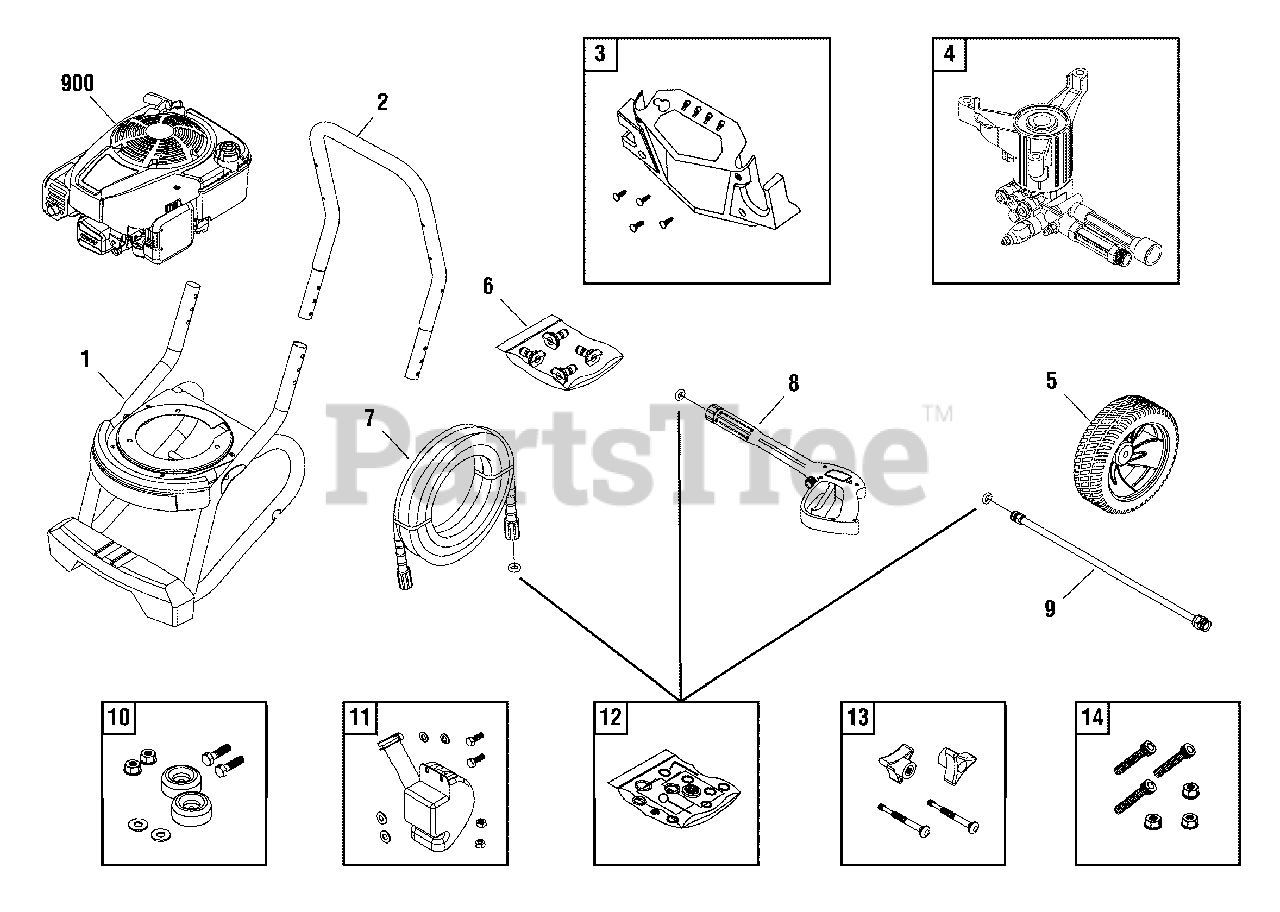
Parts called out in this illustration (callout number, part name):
6	KIT, QC Nozzles
7	HOSE
8	GUN
9	EXTENSION, QC
10	MOUNT, Vibration
12	KIT, O-Rings
13	KIT, Hardware, Handle
14	KIT, Hardware, Pump Mounting
900	* ENGINE
